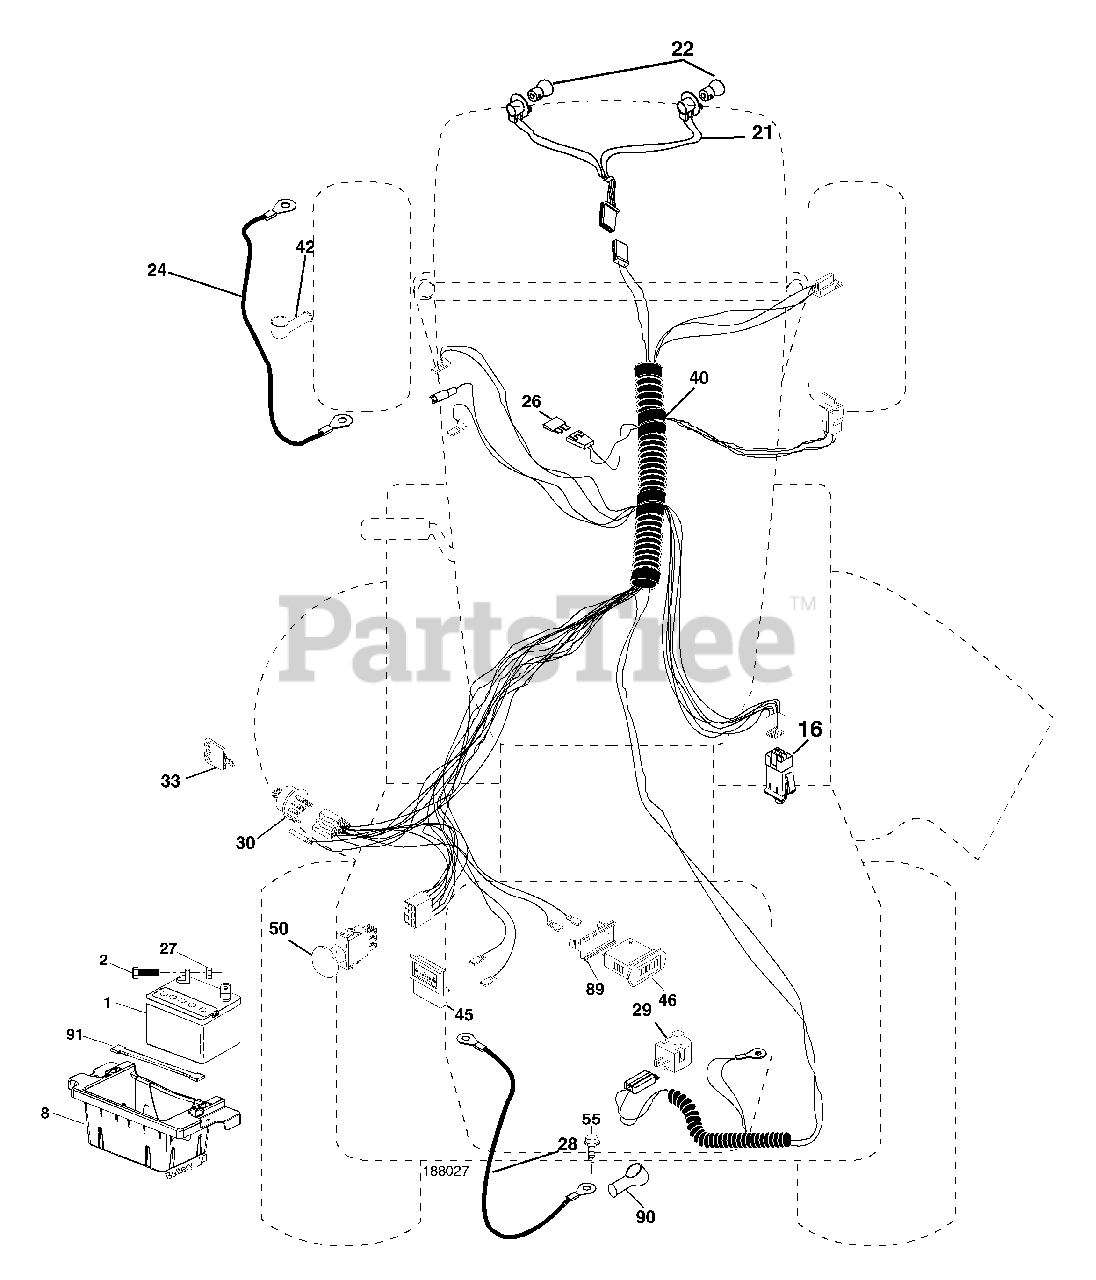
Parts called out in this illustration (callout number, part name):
1	Battery 12 Volt 35 AMP
2	Bolt Hex Hd 1/4-20 unc x 3/4
8	Box Battery
16	Switch Interlock
21	Harness Asm Light W/4152j
22	Bulb Light #1156
24	Cable Battery
27	Nut Keps Hex 1/4-20 unc
28	Cable Ground 6 Ga 21" black
29	Switch Plunger Nc Gray
30	Switch Ign
33	Key Ign Molded Generic
40	Harness Ign.
42	Cover Terminal Red
45	Ammeter Rectangular 15 Amp
46	Meter Hour
50	Switch PTO
55	Screw Thdrol 5/16-18 x 1-1/2 Tyt
89	Bracket Snap-In Hourmeter
90	Cover Terminal Battery
91	Strap Battery
